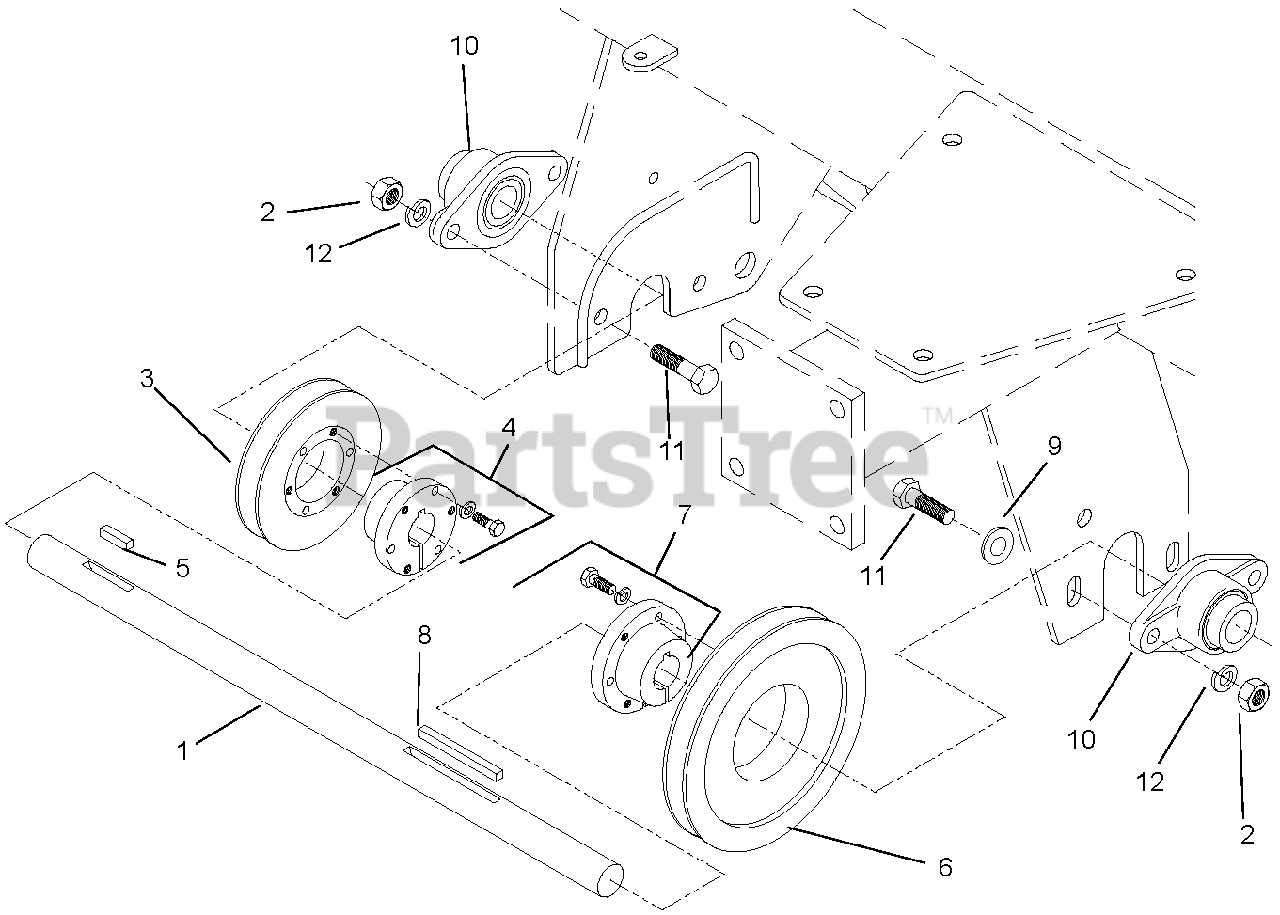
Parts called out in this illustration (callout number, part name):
1	Jackshaft, Rear 3-Gang
2	Nut, Hex .437
3	Pulley, Taper Lock 1B
4	Bushing, Split Tapered
5	Key, Square .25 x .25 x 1-Inch
6	Pulley, 1-Belt 6.6 PD
7	Bushing, Split Tapered
8	Key, .25 x .25 x 3-Inch
9	Washer, Flat .437
10	Lift, Sheave Bearing
11	Cap Screw, Hex Head .437-14 x 1.5
12	Washer, Lock .437
